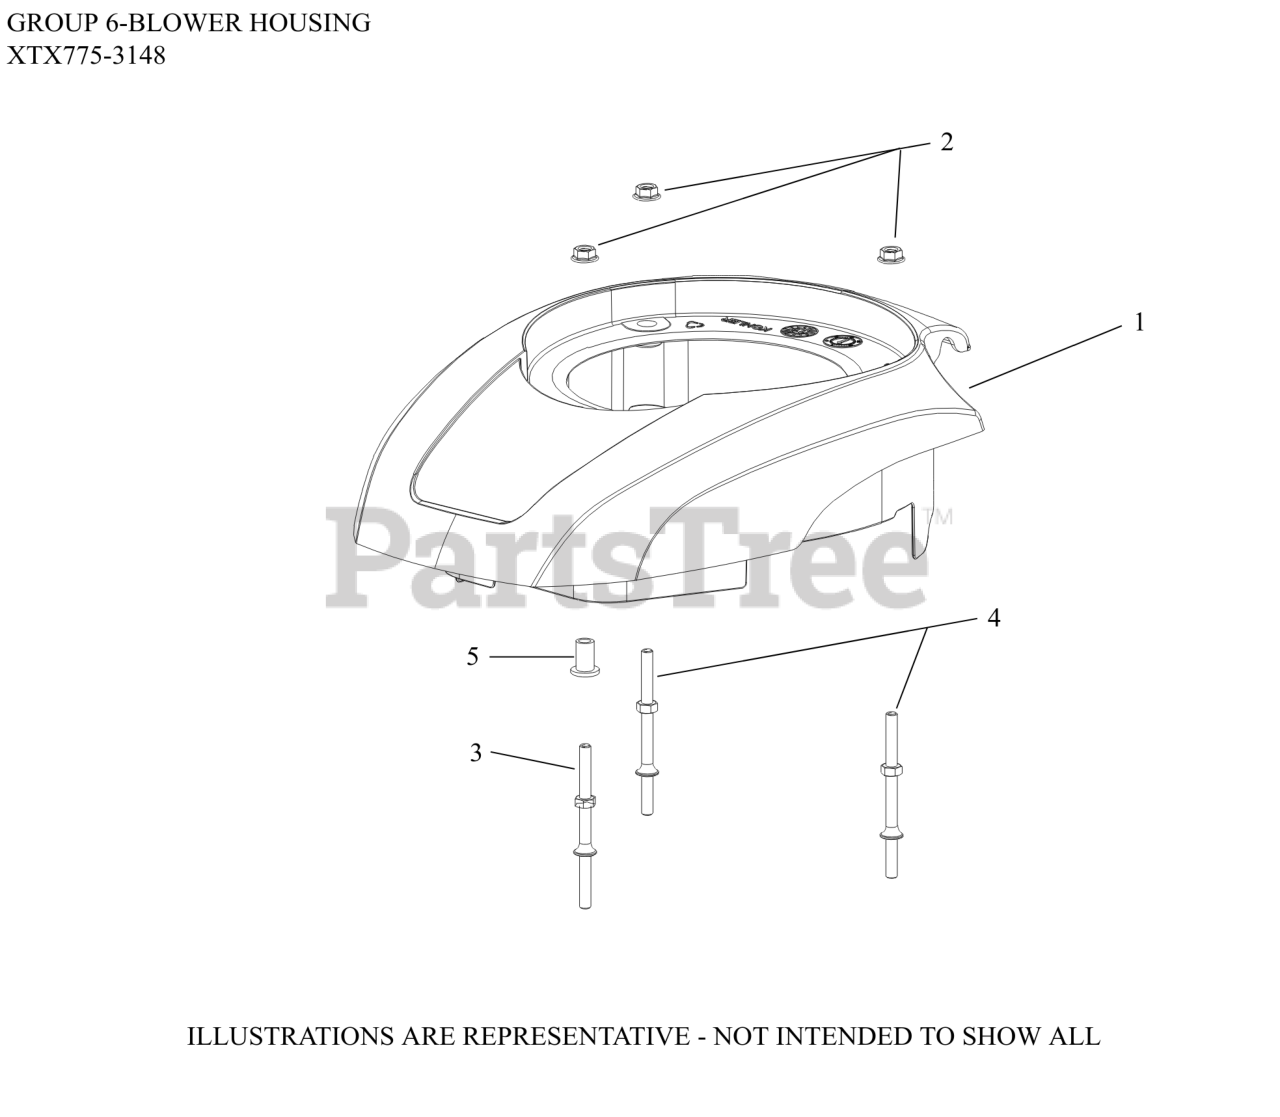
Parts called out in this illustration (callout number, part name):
1	COVER, ENGINE
2	NUT, HEX FLANGE (M6) - USE 14 100 16-S
3	STUD-USE 14 072 25-S
4	STUD-USE 14 072 26-S
